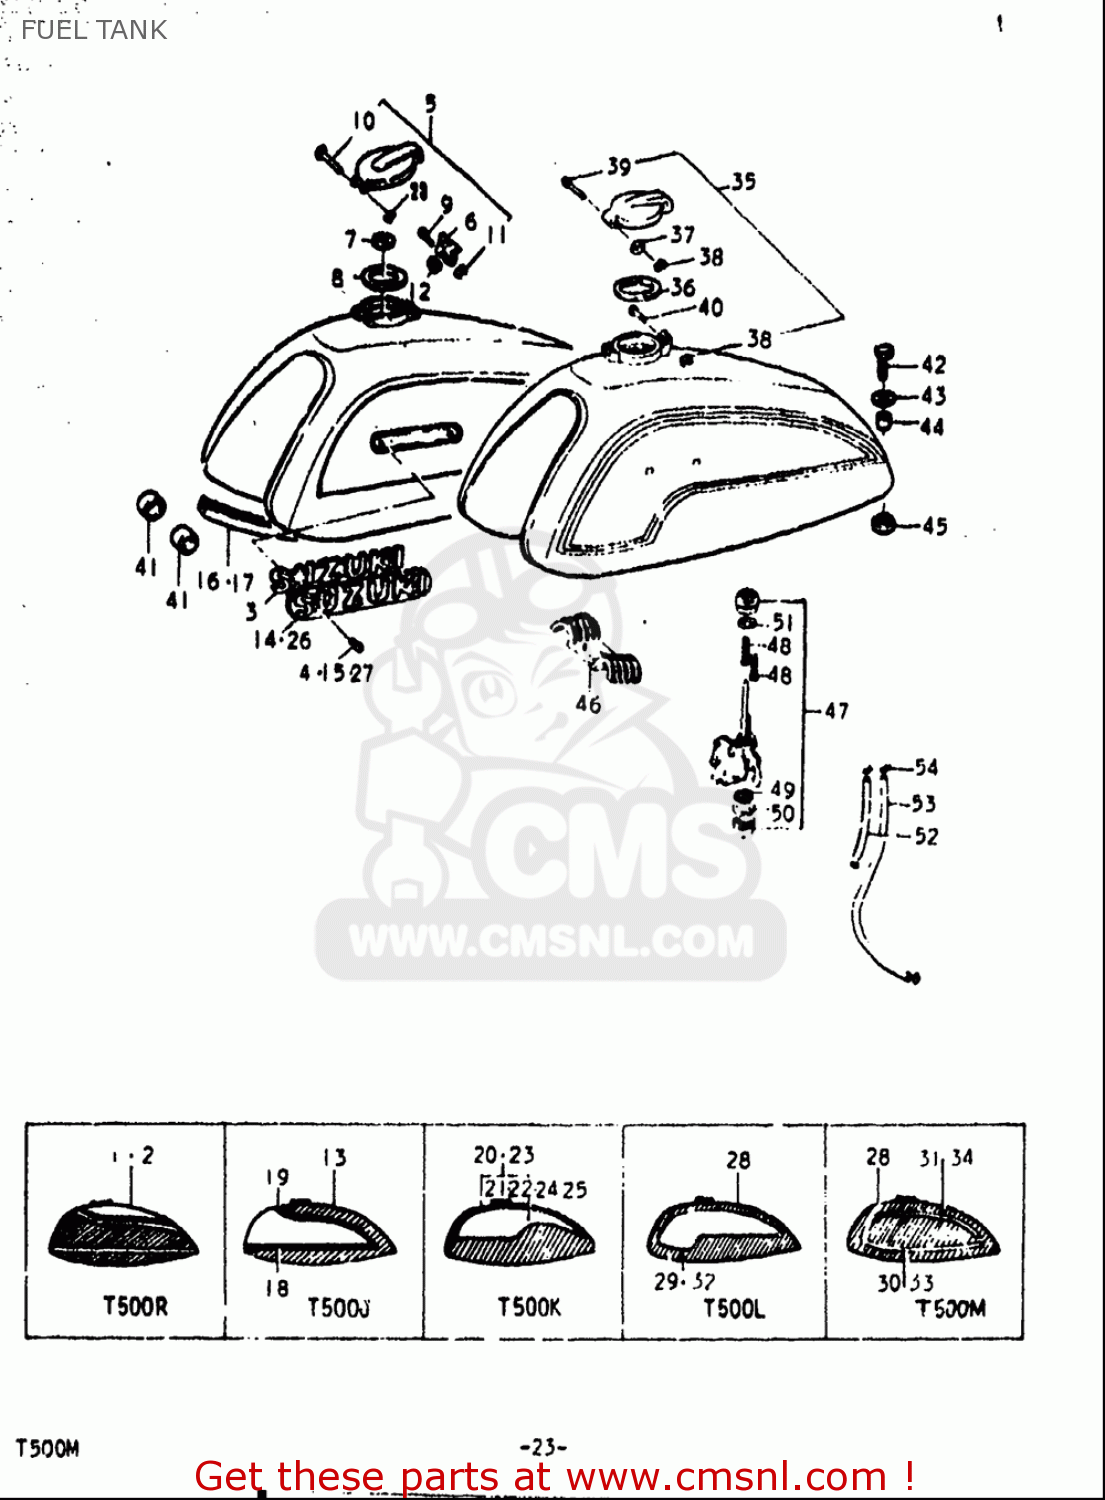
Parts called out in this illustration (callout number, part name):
4	SCREW
6	LEVER
9	PIN
11	E RING
12	SPRING
15	SCREW
27	SCREW
35	CAP ASSY,FUEL TANK
36	GASKET (NAS)
37	WASHER
38	E RING
41	CUSHION
42	BOLT
43	WASHER(8.5X28X1.6)
44	SPACER(8.5X12X11)
45	BUSH(12X15X20)
47	COCK ASSY,FUEL
50	GASKET,CLEANER CUP (NAS)
51	GASKET,FUEL COCK (NAS)
52	HOSE(5X9X600)
54	CLIP
